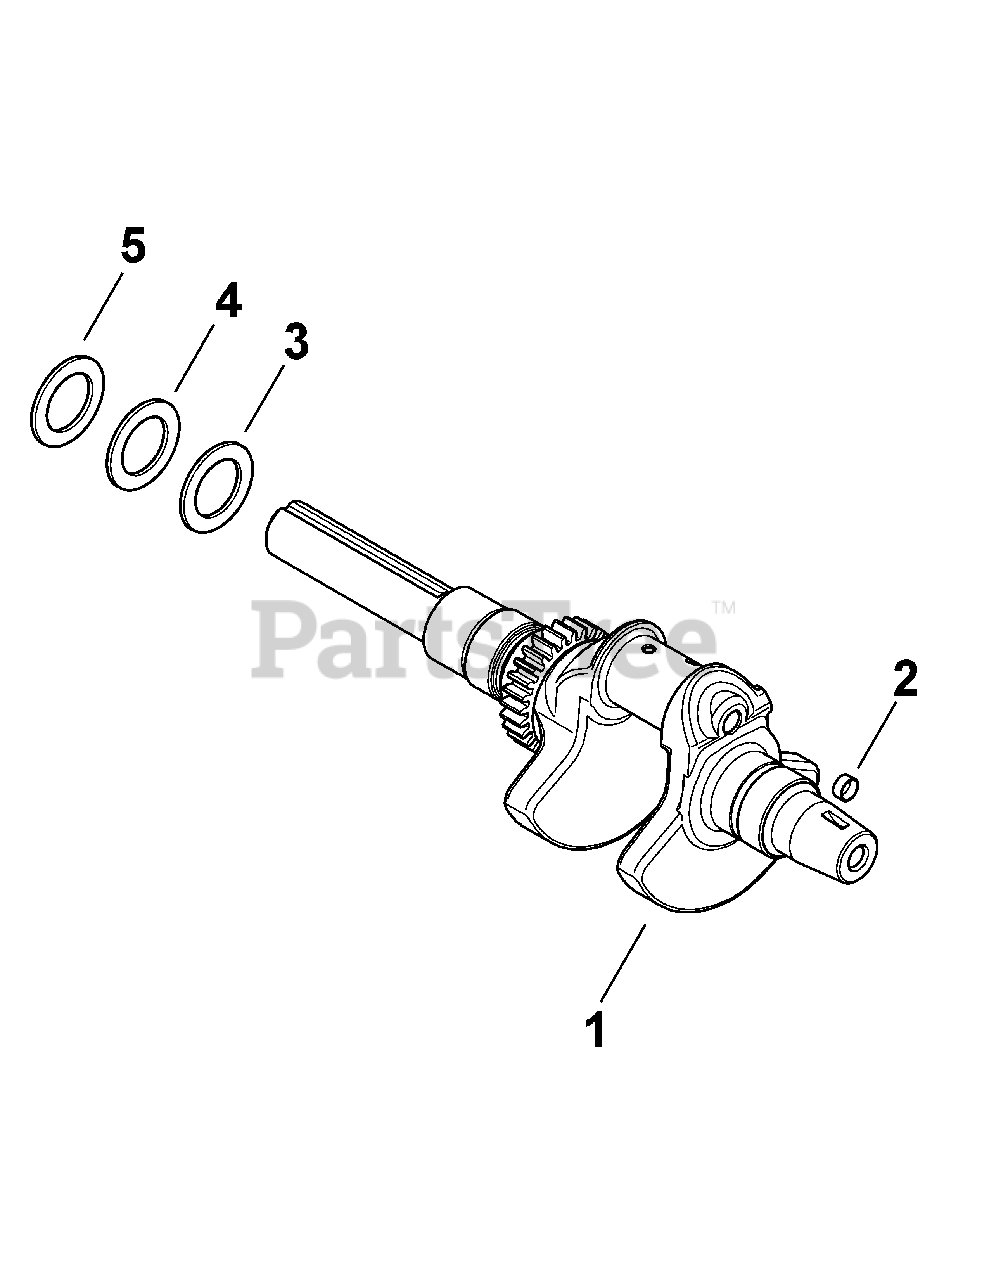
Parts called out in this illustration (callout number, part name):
1	Crankshaft
3	Not used in this application
4	Not used in this application
5	Not used in this application
